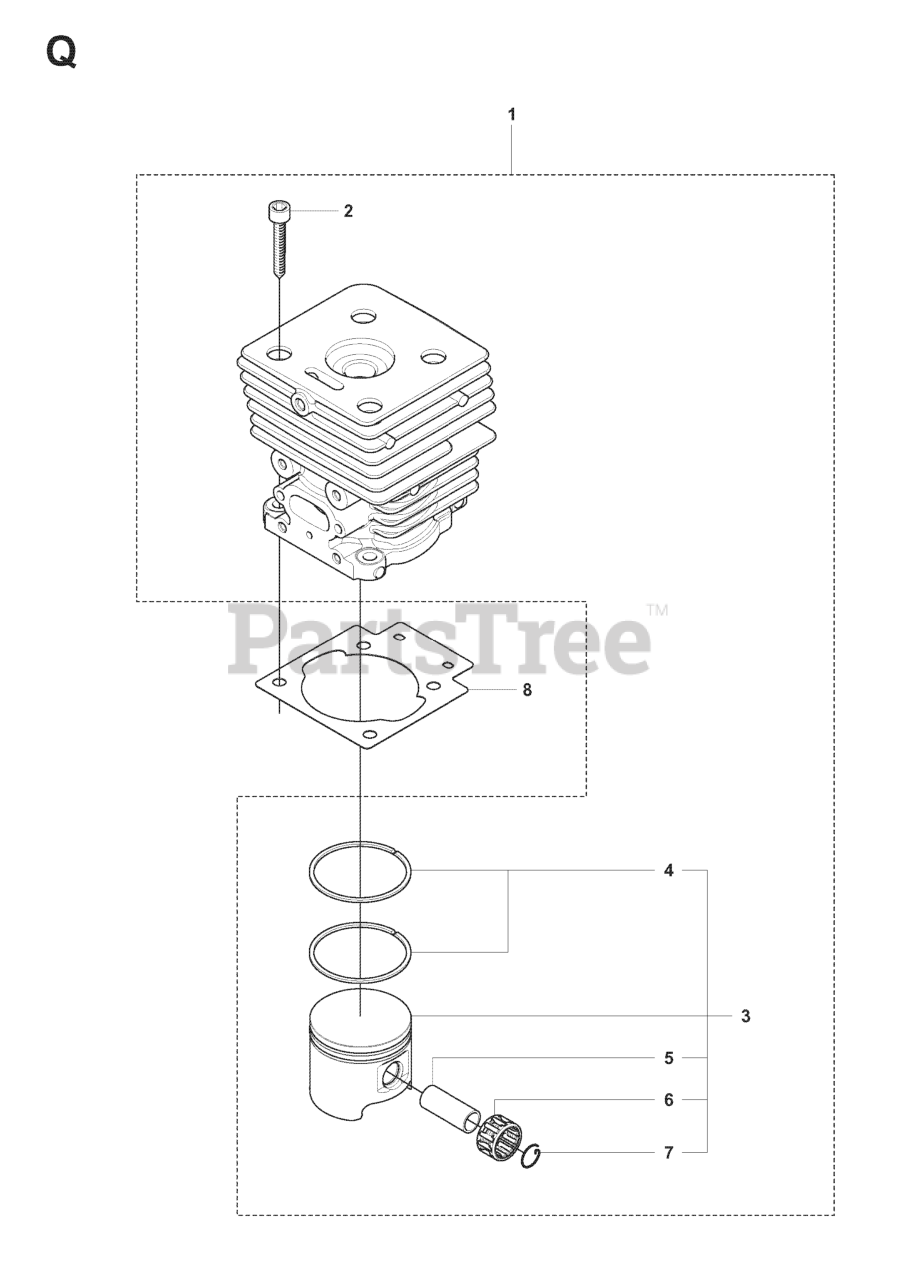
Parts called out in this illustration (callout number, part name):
1	CYLINDER ASSY
2	SCREW
3	PISTON ASSY D41 SPARE PART
4	PISTON RING D41X1.7X1.2
5	PISTON PIN 10X7X32
6	SUPPORT BUSHING
7	LOCKING RING
8	GASKET CYLINDER
